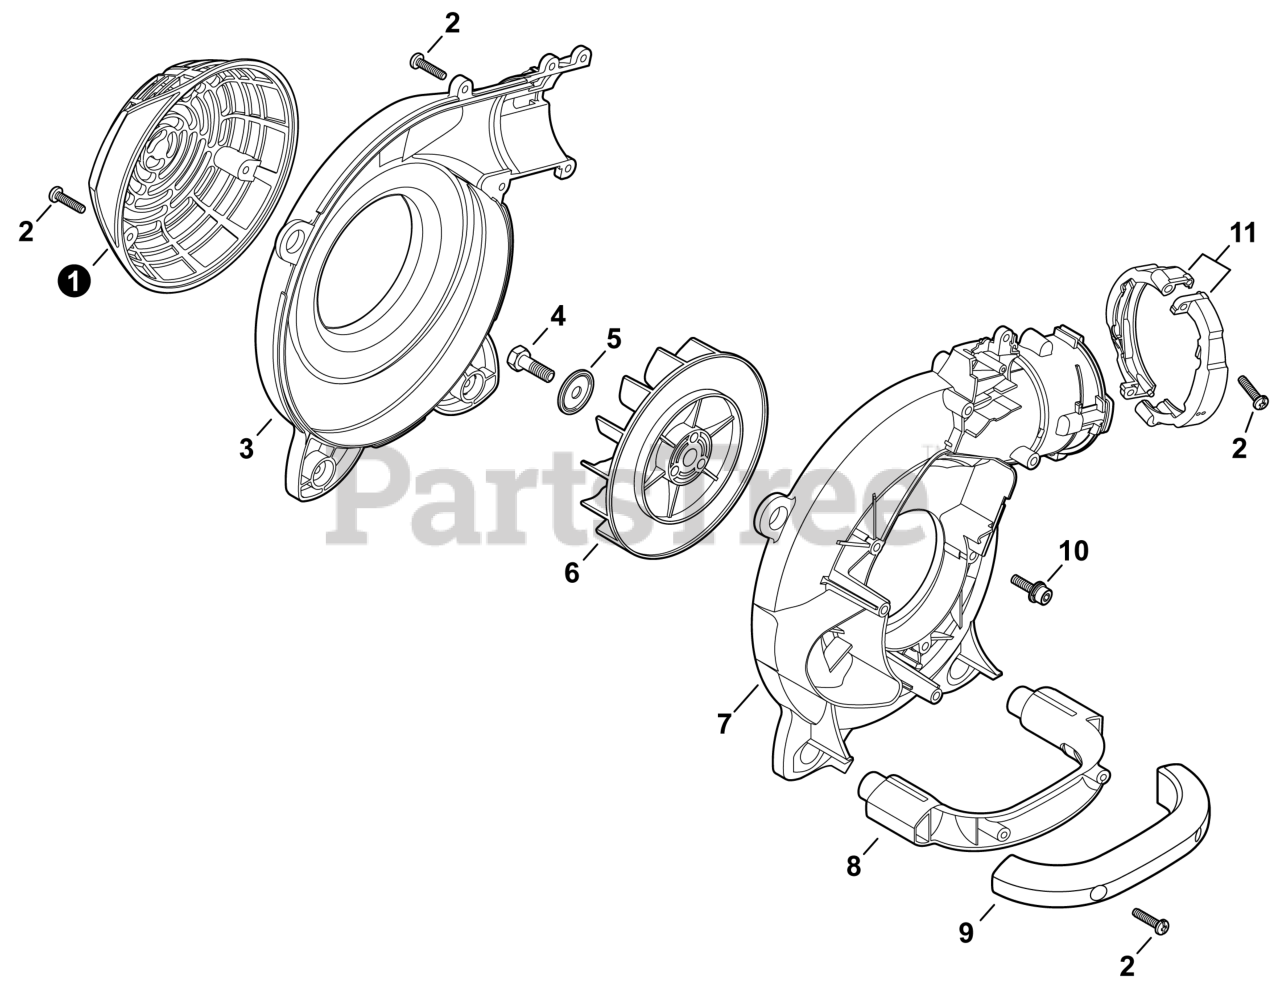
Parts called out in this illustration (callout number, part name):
1	GUARD, DEBRIS
2	SCREW, TAPPING 5×20
3	COVER, FAN
4	BOLT 8×14
5	WASHER 8.2×31×0.8
6	FAN, BLOWER
7	CASE, FAN
8	HANDLE, REAR
9	COVER, HANDLE
10	BOLT 4×20
11	COLLAR, LOCKING
